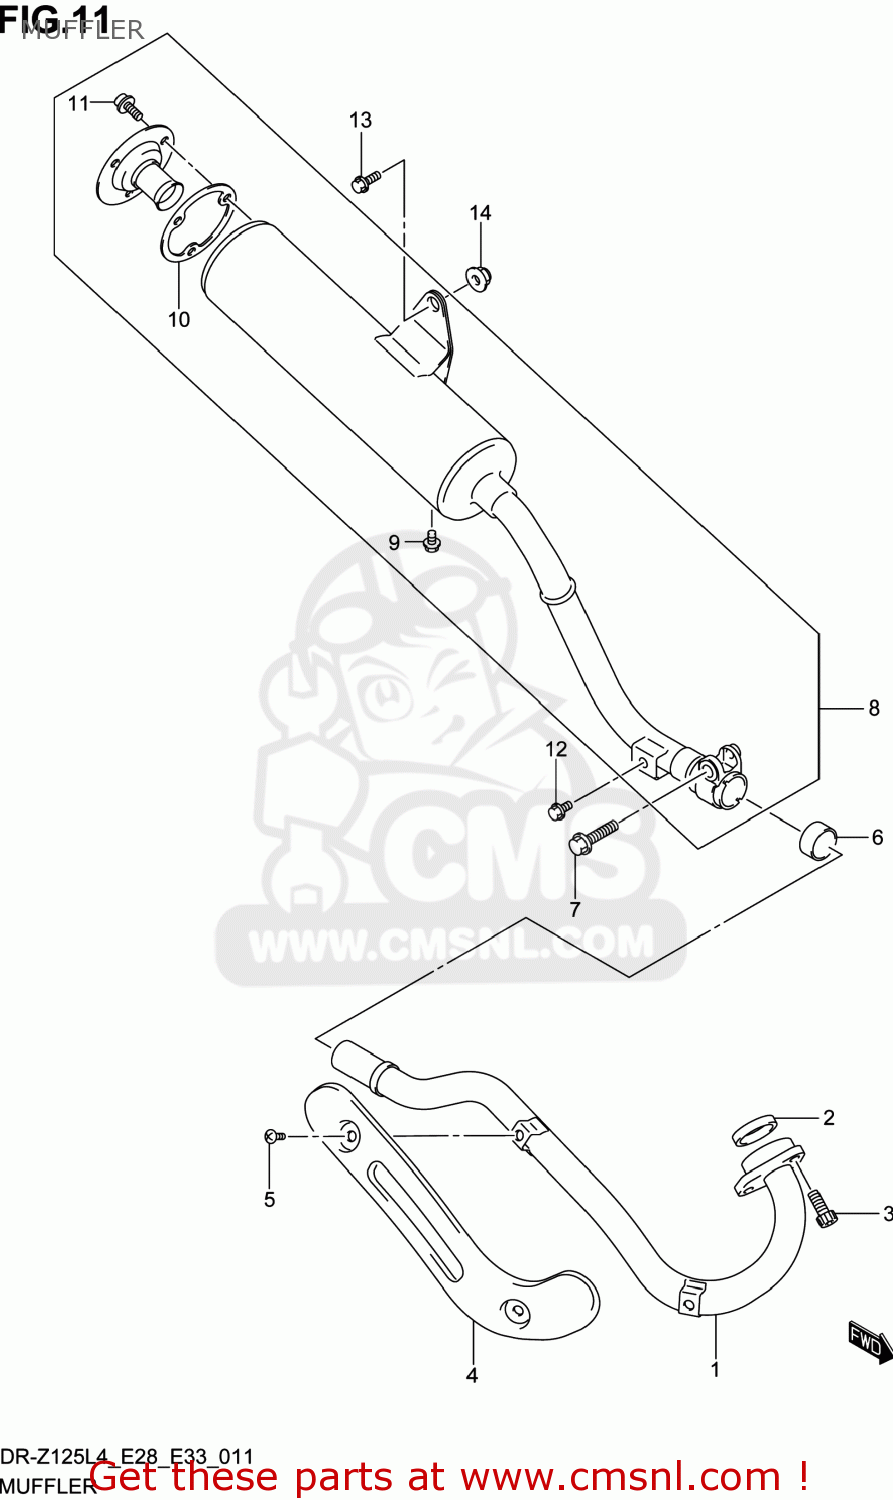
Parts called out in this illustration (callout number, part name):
1	PIPE,EXHAUST
2	GASKET (NAS)
3	BOLT
4	COVER,EXHAUST PIPE
5	SCREW(6X10)
6	CONNECTOR,MUFFLER
7	BOLT
8	BODY,MUFFLER
9	BOLT
10	GASKET,ARRESTER (NAS)
11	BOLT
12	BOLT
13	BOLT(8X23)
14	NUT
